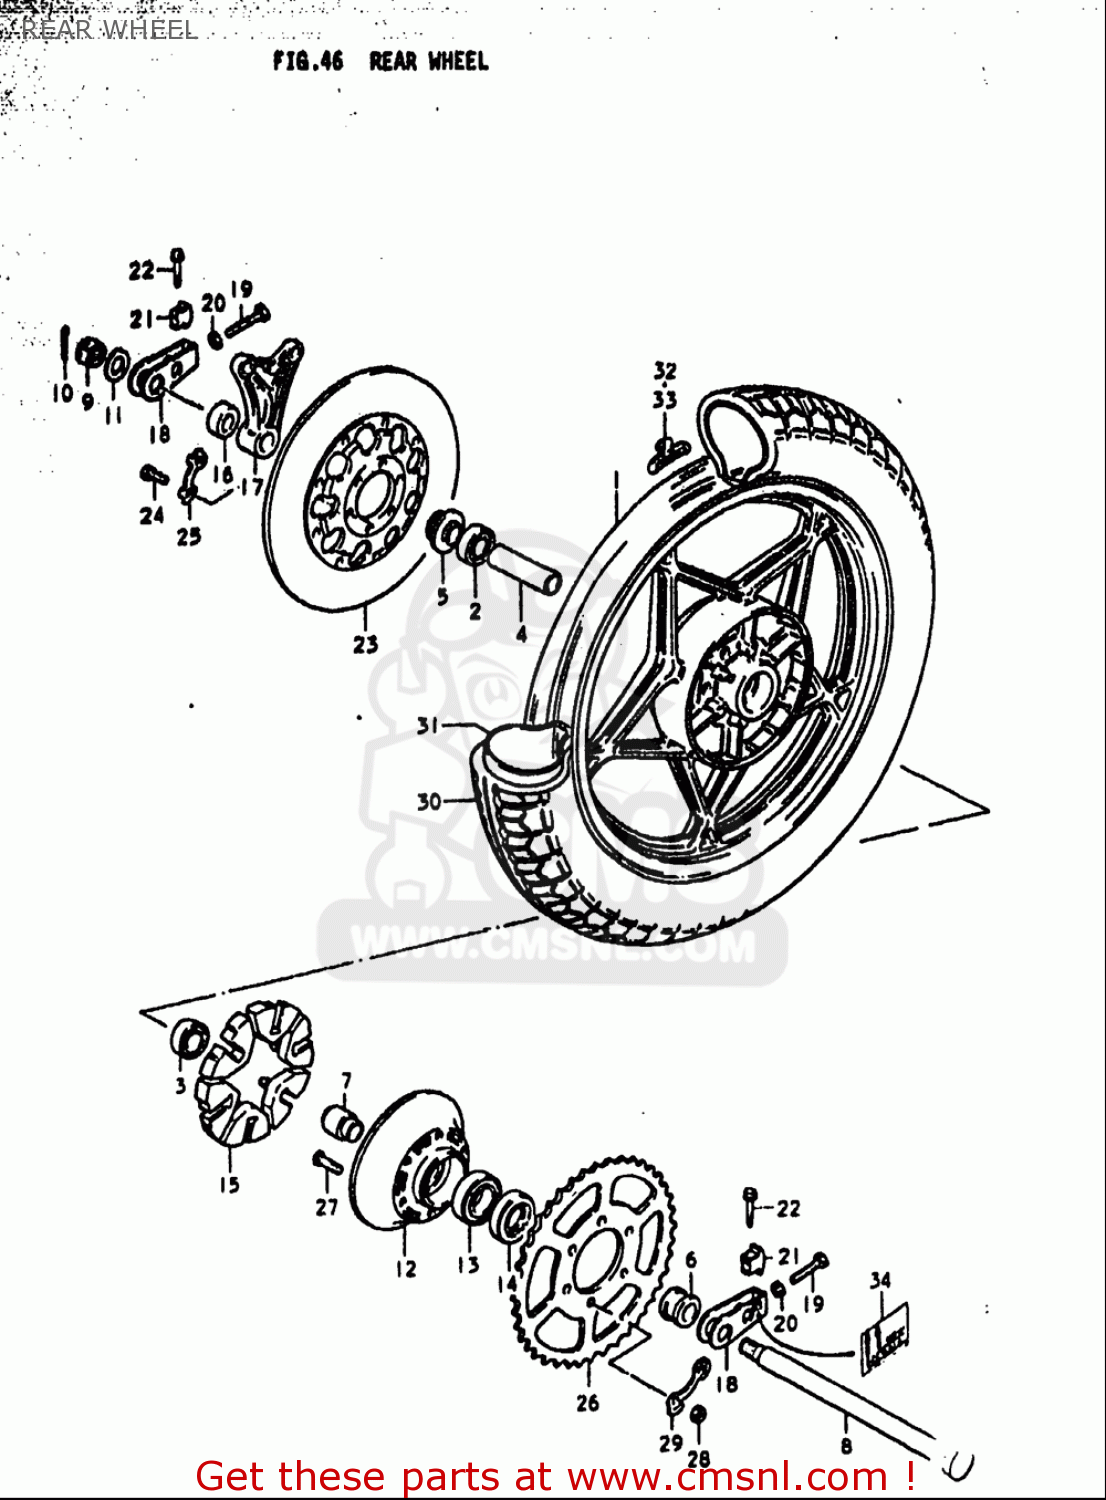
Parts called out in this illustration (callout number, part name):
2	BEARING WHEEL REAR(20X47X14)
3	BEARING(20X47X14)
5	SPACER,RR AXLE,R
6	SPACER(20X33X28.3)
7	SPACER,REAR HUB BEARING
8	AXLE,REAR
9	NUT 18MM
10	PIN
11	WASHER(19X34X4)
12	DRUM,RR SPROCKET MOUNTING
13	BEARING(25X62X17)
14	SEAL,OIL(33X62X7)
15	ABSORBER,RR HUB SHOCK
16	SPACER (20X38X17)
17	BRACKET,RR,CALIPER
18	ADJUSTER,CHAIN
19	BOLT(8X50)
20	NUT
21	SUPPORTER,CHAIN ADJUST
22	BOLT
23	DISC,BRAKE
24	BOLT 8X40
25	WASHER
26	SPROCKET,RR(NT:42)
27	BOLT(10X35.5)
28	NUT
29	WASHER
31	TUBE,INNER
32	BALANCER,WHEEL
34	LABEL,CHAIN WEAR INDICATOR
